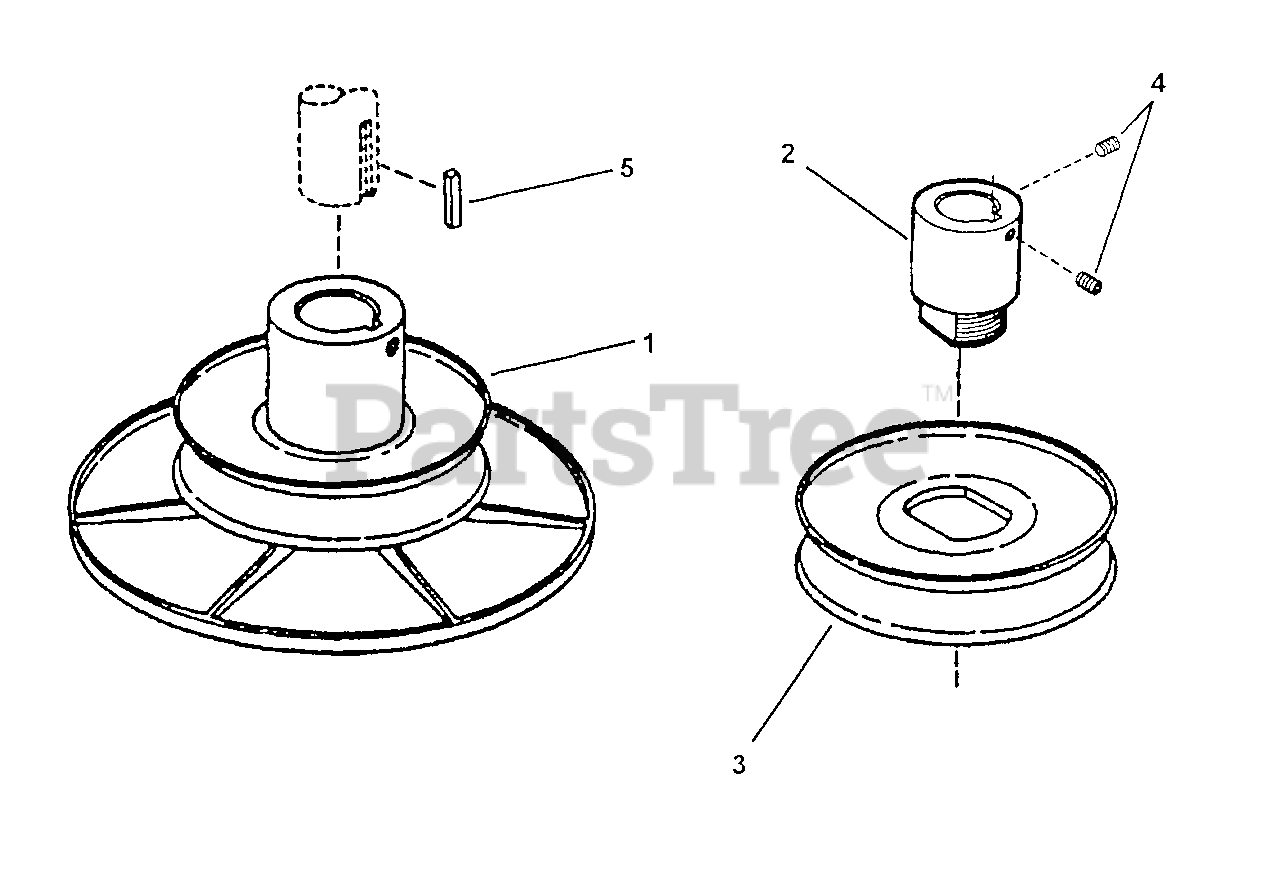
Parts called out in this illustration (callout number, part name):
1	ASSEMBLY, 5.18" O.D. Drive Disc
1	ASSEMBLY, 6" O.D. Drive Disc
3	PULLEY, Drive (5.75" O.D.)
3	PULLEY, Drive (5.18" O.D.)
4	SCREW, 3/8-16 x 3/8" Set
5	KEY, 1/4" Square x 2"
